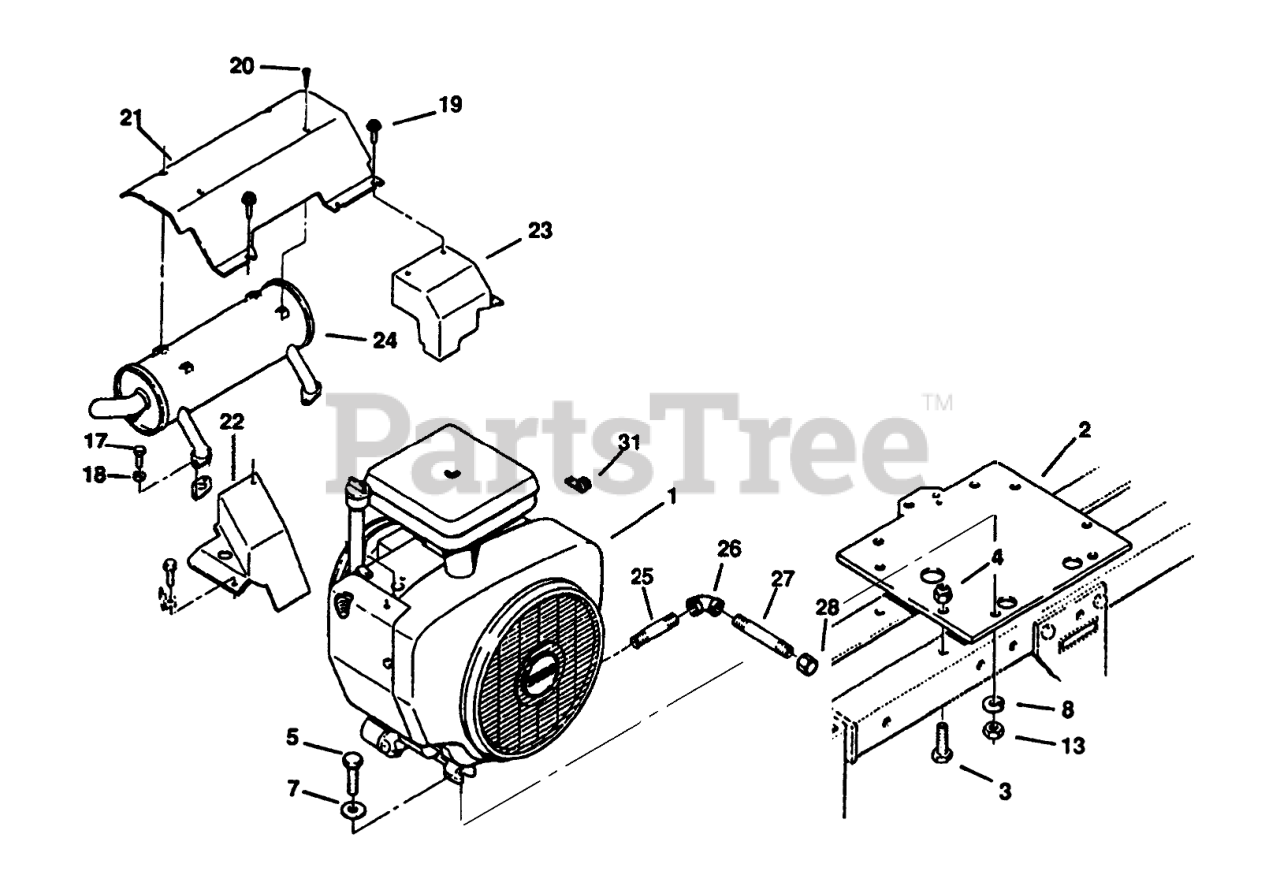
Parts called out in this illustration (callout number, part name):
1	Engine-16HP TORO Power Plus P216G-I/10976D
2	PLATE-ENGINE B
7	WASHER-FLAT
8	WASHER-LOCK/SP
13	NUT-HEX
17	SCREW-HH
18	WASHER-LOCK
19	SCREW-HH
20	Screw
21	Air Deflector
22	LH Exhaust Cover
23	RH Exhaust Cover
24	MUFFLER-EXHAUST
25	Pipe
26	ELBOW 3/8 90 DEG
27	PIPE-NIPPLE 3/8 X 4"
28	Cap
30	Exhaust Gasket
31	J-CLIP
